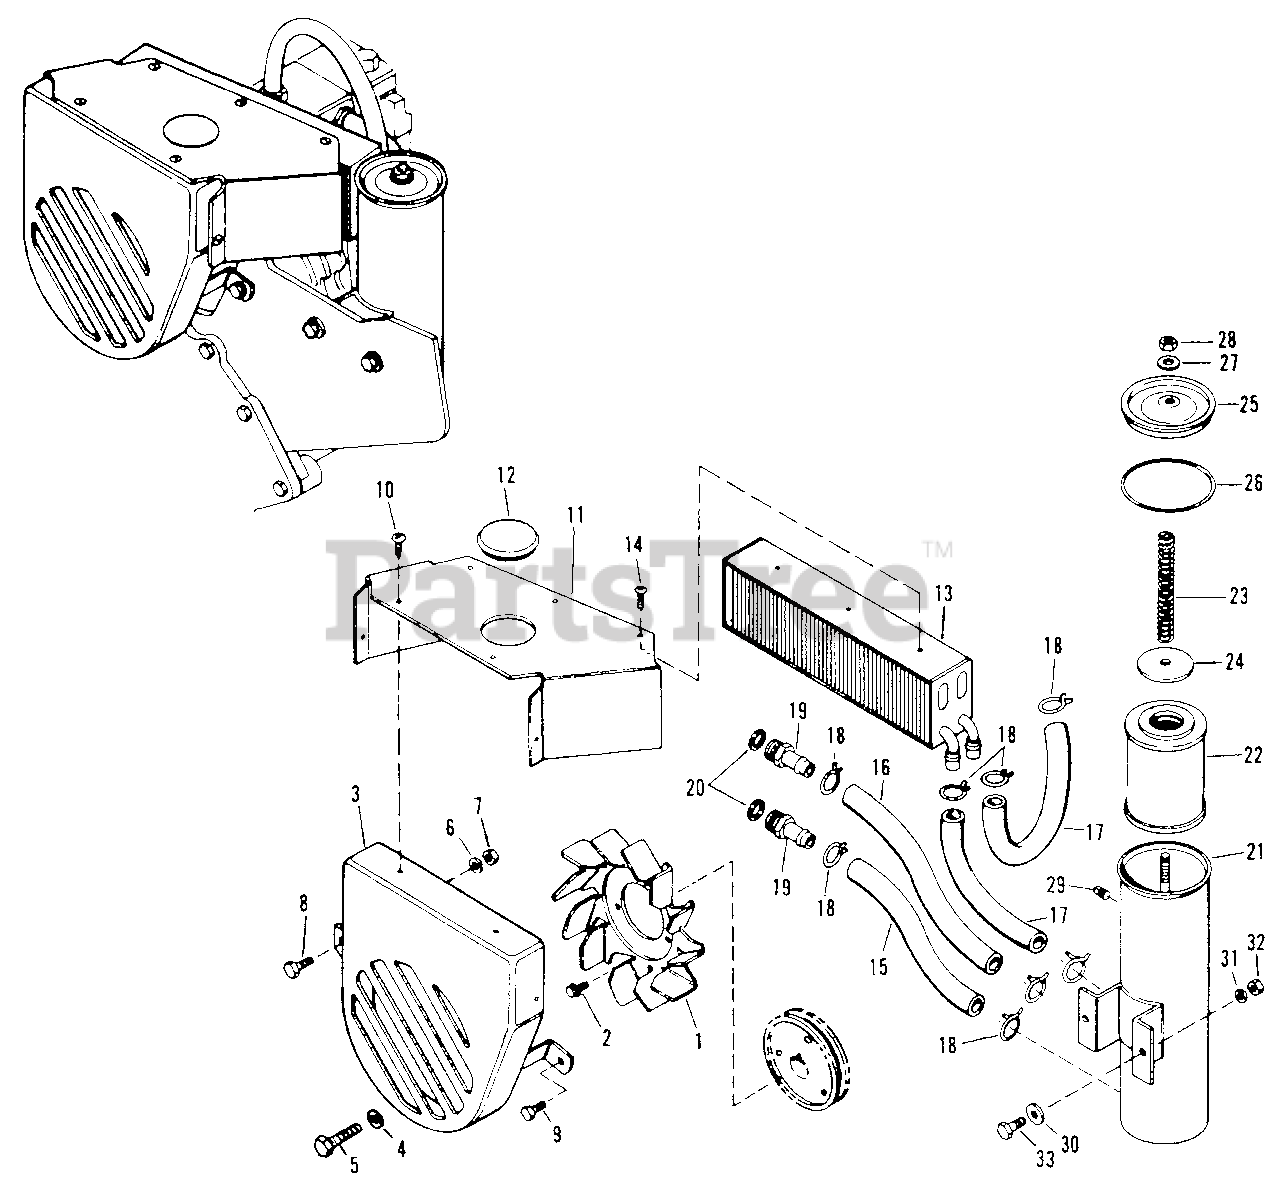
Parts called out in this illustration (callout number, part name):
2	Hex Screw, Washer Hd.
3	Fan Shroud Assembly
4	Lockwasher
5	Hex Capscrew, 3/8"-16 x 7/8"
6	Lockwasher, 5/16"
7	Full Hex Nut, 5/16"-18
8	Hex Capscrew, 5/16"-18 x 3/4"
9	Hex Hd. Thread Forming Screw
10	Self Tapping Screw, No. 10 x 3/8"
11	Cooler Deflector
13	Oil Cooler
14	Rd. Hd. Machine Screw, No. 10-32 x 1/2"
15	Hydraulic Hose
16	Hydraulic Hose
17	Hydraulic Hose
18	Hose Clamp
19	Beaded Insert
21	Reservoir Assembly
22	Filter Element
25	Reservoir Cover
27	Nylon Washer
28	Elastic Stop Nut
29	Pipe Plug, 1/4"
30	Plain Washer, 5/16"
31	Lockwasher, 5/16"
32	Full Hex Nut, 5/16"-18
33	Hex Capscrew, 5/16"-18 x 3/4"
